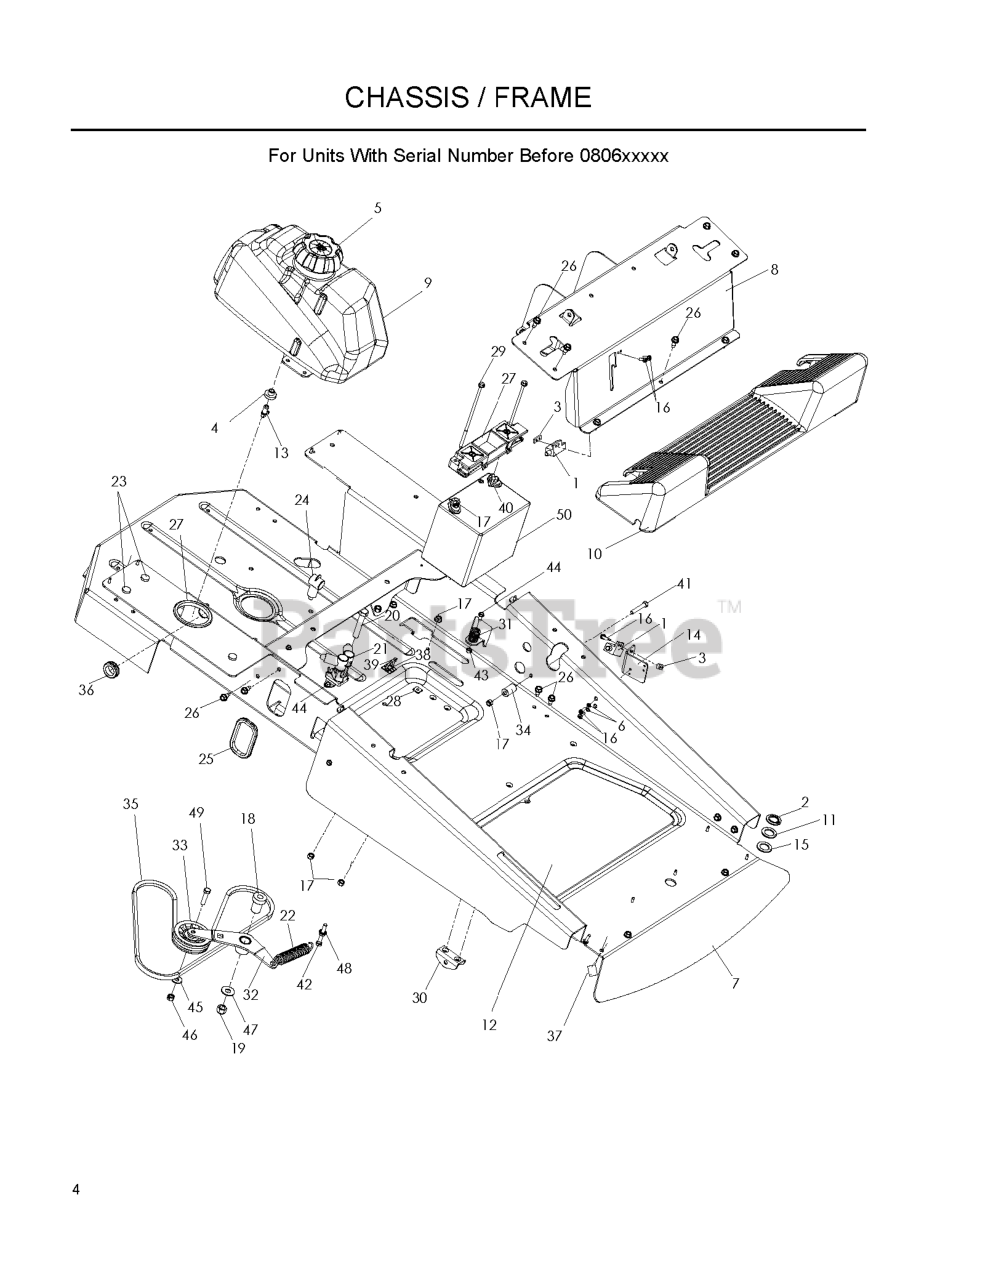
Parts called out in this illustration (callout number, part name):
1	SWITCH, INTERLOCK
2	RETAINING RING, 7/8"
3	TAPPED PLATE
4	RUBBER GROMMET
5	FUEL CAP ANTI-SPLASH
6	WASHER - 3/16 LOCK ZD
7	FRAME W/DECALS
8	CONSOLE W/DECALS
10	FOOT REST GRAY
12	SLIP, MATTING
13	STEM, FUEL TANK
15	BSHG .875 X 1.375 X .074 ZD
16	SCREW #10-24 X 5/8
17	NUT 5/16 NYLOC
18	IDLER SPINDLE
19	NUT 1/2-13 HEX NYLOC ZD
20	HCS 1/2C X 2 3/4
23	GROMMET, BUMPER
26	BOLT 5/16-18 X 3/4
27	BATTERY HOLD DOWN
28	PUSH NUT-NYLON
29	BOLT - 1/4-20 X 7.5
30	BRACKET, DECK HANGER
31	SPRING, RETURN TO NEUTRAL
32	PUMP IDLER WELDMENT
33	PULLEY, IDLER RAKE & ZTR
34	MOTION LIMITER
35	BELT, HYDRO PUMP
36	GROMMET, FUEL LINE
37	SCR #10-12X1-1/2HEX WASH HD ZD
38	MOUNTING BLOCK CABLE TIE
39	TIE, PLASTIC
40	HCS 5/16C X 3/4
41	HCS 5/16-18X2
43	NUT.1/4-20.HEX.NYLOC.ZD
44	SCREW 1/4 X 5/8
45	WASHER 3/8 FLAT
46	NUT 3/8C CENTERBLOCK
47	WASHER 1/2 FLAT
48	NUT 5/16C WHIZ
49	HCS 3/8C X 1 1/2
50	BATTERY, 12 V 330 AMP
